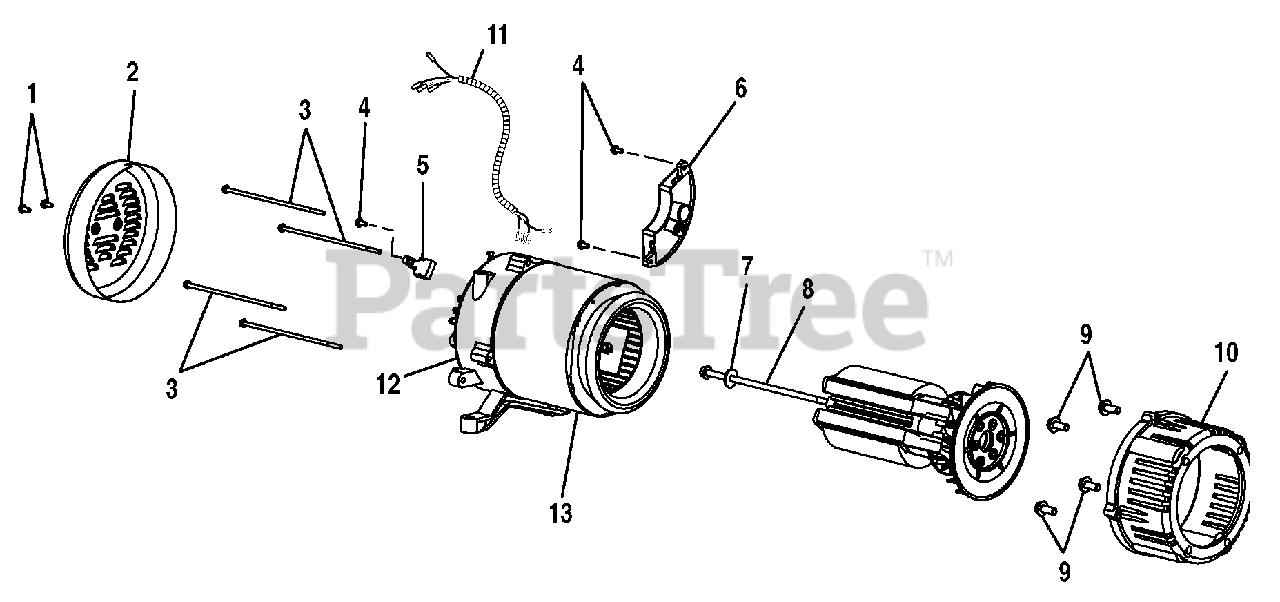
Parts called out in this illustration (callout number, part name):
2	Brush Cover
3	Bolt (M6 x 164 mm)
5	Brush Assembly
6	Automatic Voltage Regulator
7	Washer ( 5/16 in.)
8	Bolt (5/16-24 x 215 mm, Hex. Hd.)
9	Bolt (3/8-18 x 1-1/4 in.)
10	Engine Adapter
11	Wiring Harness
12	Bearing Support
13	Generator Head Cover
